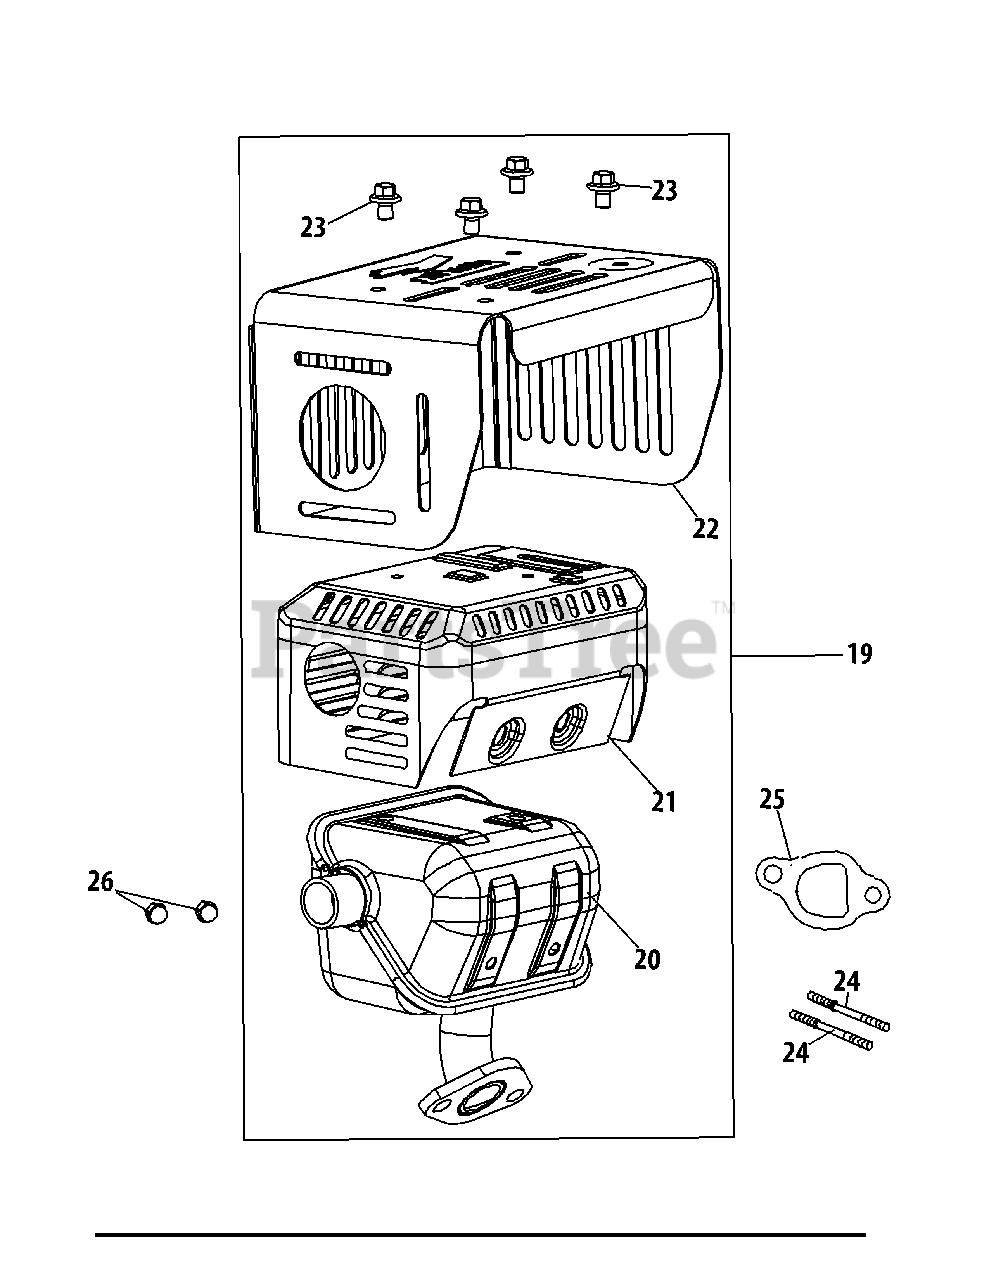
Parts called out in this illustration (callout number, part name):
19	Muffler Assembly
20	Muffler Body
21	Muffler Shield
22	Muffler Guard
23	Bolt M5×8
24	Stud M8×34
24	Muffler Stud Assy
25	Exhaust Pipe Gasket
